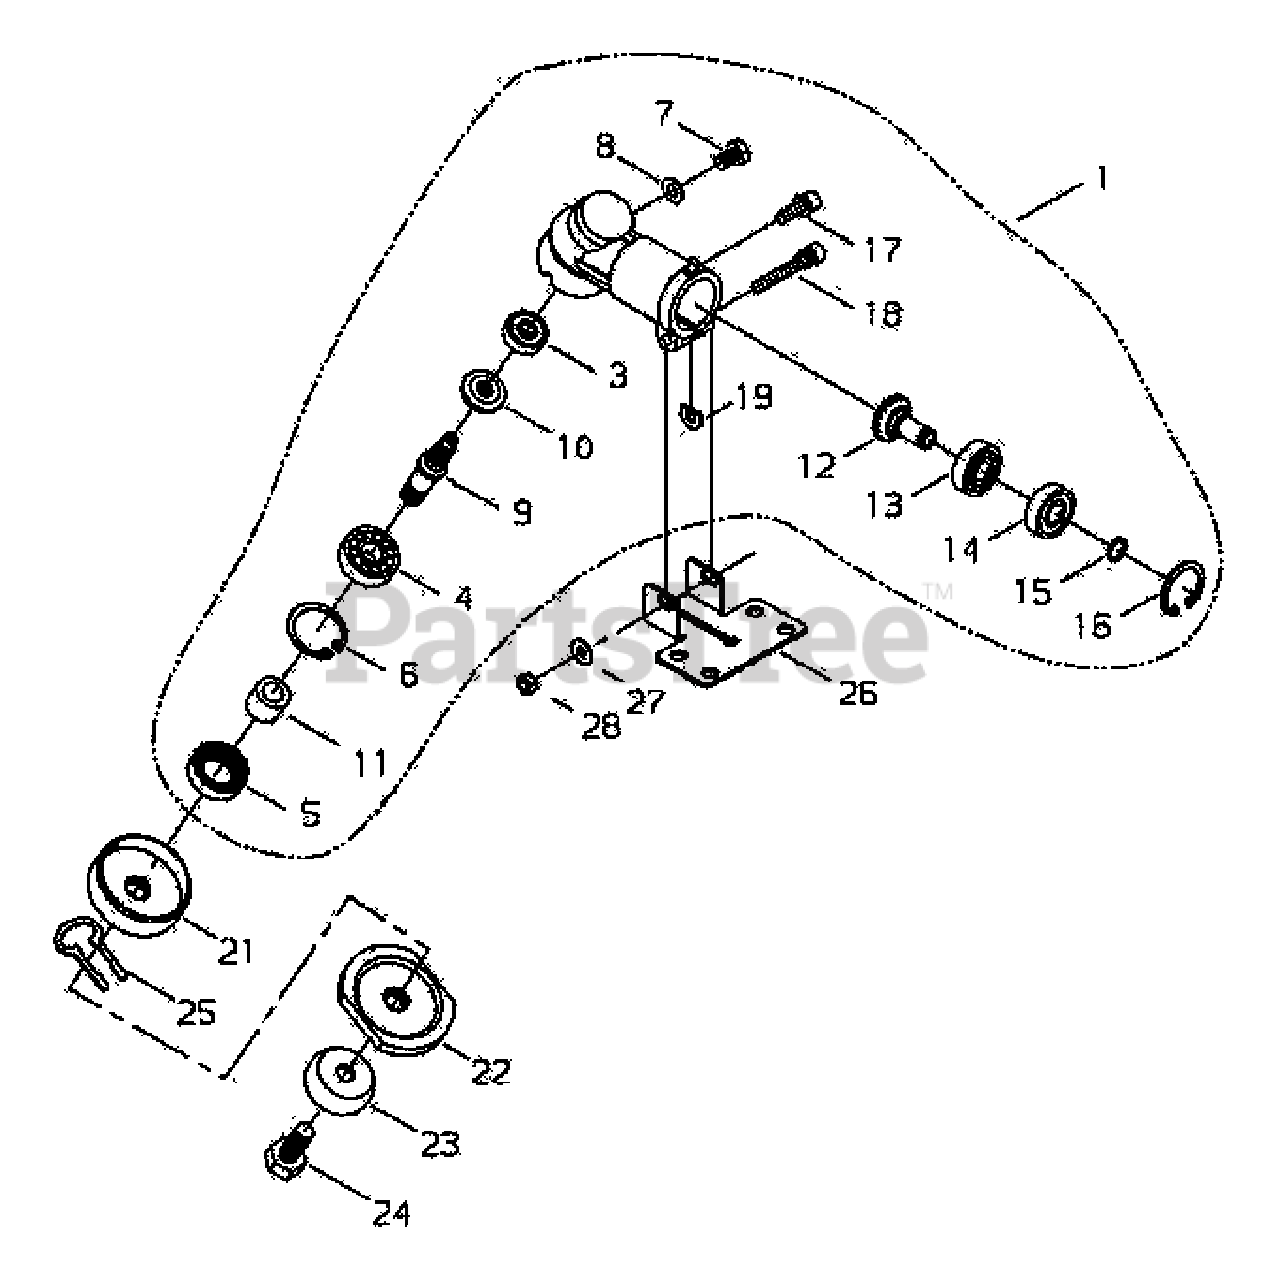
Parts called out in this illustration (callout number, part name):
1	GEAR CASE ASSY
3	BEARING, BALL 626 DDU
4	BEARING, BALL 6000
5	SEAL, OIL
6	RING, SNAP Ø26
7	BOLT M6×10
8	WASHER
9	SHAFT, GEAR
10	GEAR, BEVEL
11	SPACER
12	GEAR, PINION
13	BEARING, BALL 608
14	BEARING, BALL 608ZZ
15	RING, SNAP
16	RING, SNAP Ø22
17	BOLT M5×16
18	BOLT M5×35
19	D-WASHER
21	PLATE, ADAPTOR - UPPER
22	PLATE, ADAPTOR - LOWER
23	GUARD, BOLT
24	BOLT M7×18
25	CLIP, BLADE
26	PLATE, SHIELD MOUNTING
27	WASHER 5 MM
28	NUT M5
